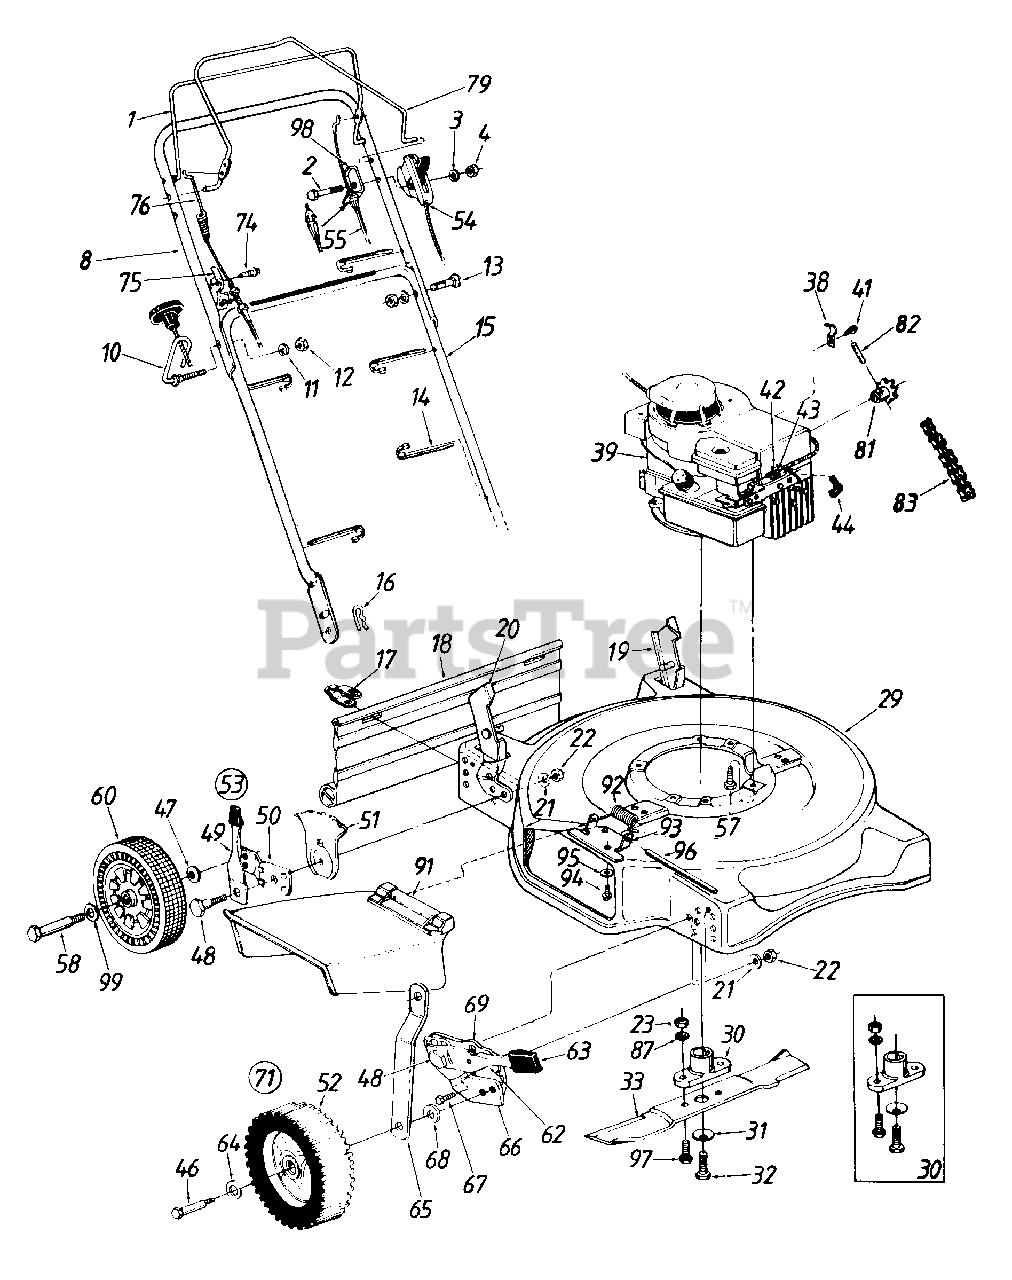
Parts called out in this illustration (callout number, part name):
1	Control Handle
2	Hex Bolt 1/4-20 x 1.75" Lg.
3	Spr. Wash. .265" I.D. x .562" O.D.
4	Hex Nut 1/4-20 Thd.
8	Upper Handle
10	Rope Guide Bolt
11	L-Wash. 5/16" I.D.
12	Hex Nut 5/16-18 Thd.*
13	Curved Carriage Bolt 5/16-18 x 1.38" Lg.
14	Cable Tie
15	Lower Handle
16	Hairpin Cotter
17	Hinge Clip
18	Rear Flap
19	Handle Bracket Ass'y.-L.H.
20	Handle Bracket Ass'y.-R.H.
21	Bell-Wash. .39" I.D. x 1.38"
22	Hex Nut 3/8-16 Thd.
23	Hex Nut 3/8-24 Thd.
29	22" Deck Ass'y.
30	Blade Adapter Kit
31	Bell-Wash..39" I.D.
32	Hex Bolt 3/8-24 x 1.5" Lg.
33	22" Blade
38	Cable Clamp
39	Engine
41	Hex B-Tap Scr. #10 x .38"
42	Cable Clamp
43	Hex AB-Tap Scr. #8 x 38" Lg.
44	Spark Plug Boot
46	Front Axle Bolt
47	Bell-Wash. .400" I.D. x .88'
48	Shld. Bolt .50" Dia. x .357"
49	Spring Lever Ass'y. w/Knob
51	Height Adj. Plate
52	Front Wheel Ass'y. Comp.
53	Height Adj. Ass'y. Comp.-R.H.
54	Throttle Control Ass'y. Comp. 51.62" Lg.
55	Control Cable - 39"
57	Hex L-Wash. Hd. Scr. 3/8-16 x 1.0" Lg.
58	Rear Axle Bolt
60	Rear Wheel Ass'y. Comp.
62	Spring Lever
63	Spring Lever Knob
64	Fl-Wash. .531" I.D. x .93"
67	Hex AB-Tap 1/4-.62" Lg.
68	Bell-Wash. .380" I.D. x .88"
69	Index Plate
71	Front Height Adj. Ass'y.-R.H.
74	Hex Wash. AB-Tap Scr. 5/16 x.75" Lg.
75	Cable Brkt.
76	Clutch Cable w/Spring-47"
79	S.P. Bail Ass'y.
81	10 Tooth Sprocket Ass'y.
82	Spring Pin Spir. 8/16" Dia. x 1" Lg.
83	#48 Chain 1/2" Pitch 50 Links
87	L-Wash. 3/8" I.D.
91	Chute Deflector Ass'y.
92	Torsion Spring
93	Adapter Plate
94	Hex Self-Tap Scr. 1/4-20 x .5" Lg.
95	Bell-Wash. 1/4" I.D.
96	Hinge Pin
97	Hex Bolt 3/8-24 x 1" Lg.
98	Cable Mtg. Bracket
99	Wave Wash. .53" I.D. x .78"
